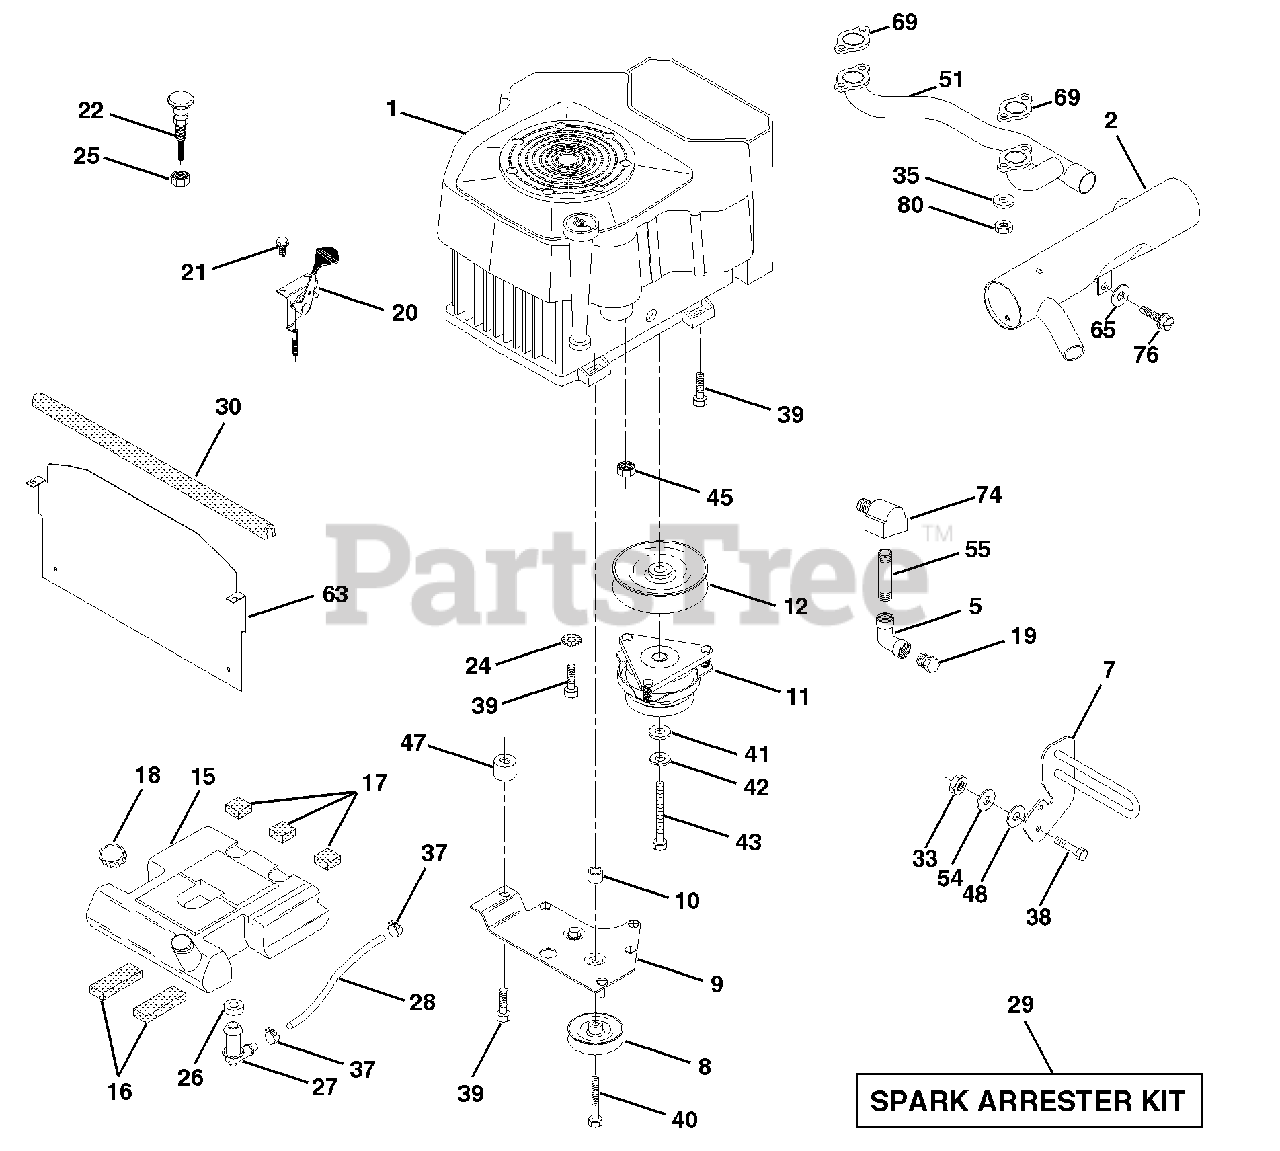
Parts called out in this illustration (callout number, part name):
2	Muffler Side 1-1/4
5	Elbow STD 90 Degree 3/8-18 NPT
7	Muffler Assembly Guard
8	Pulley V-Idler
9	Keeper Asm Belt Engine VGT 96
11	Clutch Electric
12	Pulley Engine VGT Elect Clutch
15	Tank Fuel Rear
16	Pad Spacer
17	Pad Spacer
18	Cap Asm Fuel W/Sym Vented
19	Plug Oil Drain
20	Control Throttle
21	Screw Hex Thd Cut 1/4-20 X 5/8
22	Control Choke
24	Washer Ext Tooth 3/8
25	Nut Keps 3/8 - 24 UNF
26	Bushing
27	Stem Tank Fuel
28	Fuel Line
29	Spark Arrester Kit
30	Extrusion Hood
33	Nut, Hex W/Ins. 3/8-16 UNC
35	Washer Split
37	Clamp Hose
38	Bolt, Fin Hex 3/8-16 UNC x 1-1/2
39	Screw TT 3/8-16 x 2-1/4 UNC
40	Screw TT 3/8-16 x 4 UNC
41	Washer 1-1/2 OD X 15/32 ID X .250
42	Washer Lock 7/16
43	Bolt Hex 7/16-20 X 4-1/4 Ga 5
45	Nut Flange 1/4-20 Starter Nut
47	Spacer Engine
48	Washer 13/32 x 1-1/4 x 7 Ga.
51	Manifold Pipe VGT CV 1-1/4
54	Washer Flat 13/32 x 7/8 x 14 Ga.
55	Nipple, Pipe 4-1/2
63	Shield, Heat VGT YP/Husq.
65	Washer 13/32 x 1 x 14 Ga.
69	Gasket Kohler
74	Elbow Street Brass
76	Screw Thdrol 3/8-16 x 3/4 TY-TT
80	Nut Flange M8-1.25
